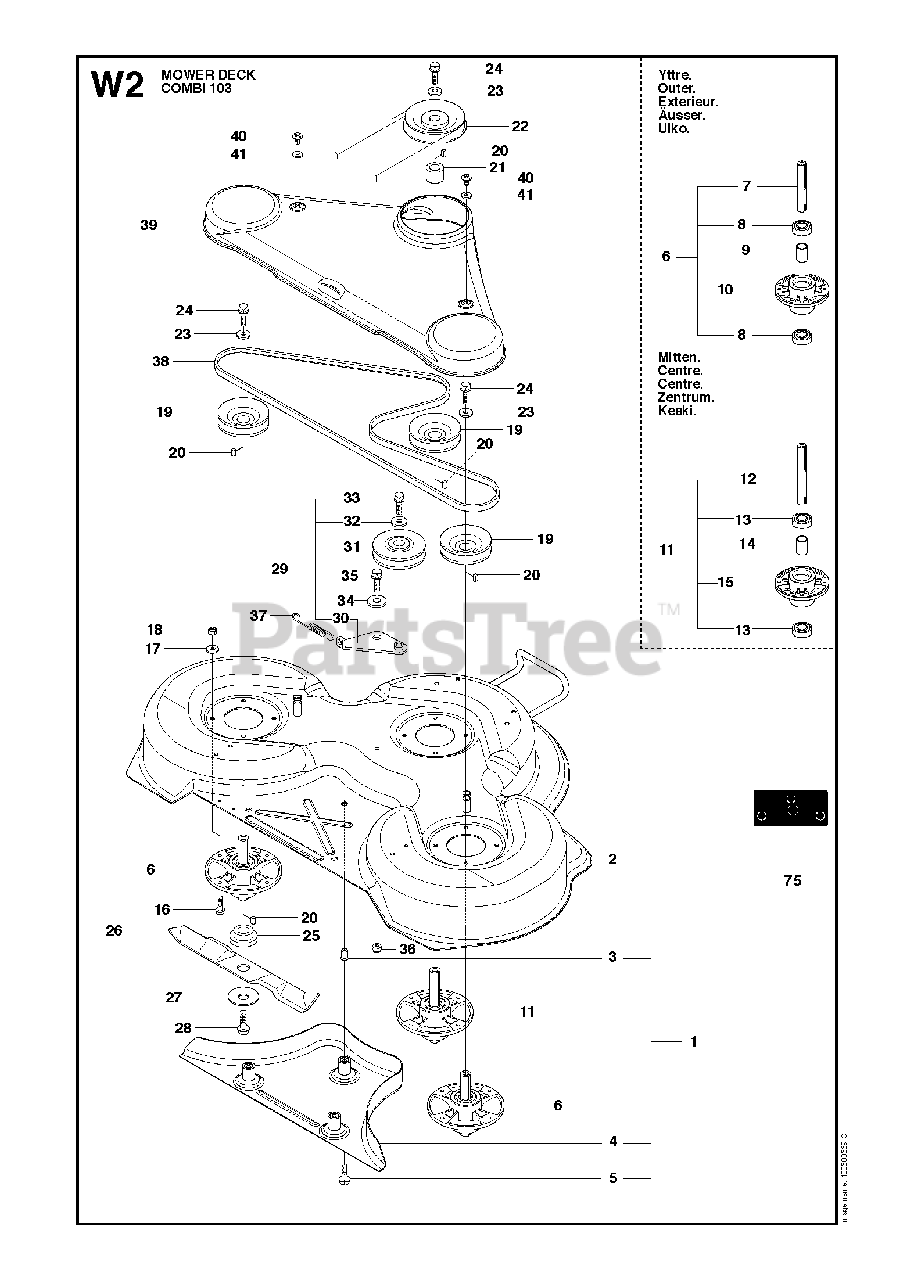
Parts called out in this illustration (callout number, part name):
3	NUT
4	PLUG
5	BOLT
6	RP SPINDLE ASSY
7	SHAFT
8	BEARING
9	SPACER
10	BEARING HOUSING
11	RP SPINDLE ASSY
12	SHAFT
13	BEARING
14	SPACER
15	BEARING HOUSING
17	WASHER BRB 8.4X17
18	LOCKNUT M8
26	BLADE
29	BELT TENSIONER ASSY
30	BELT TENSIONING ARM
31	PULLEY
32	SPACER
33	BOLT
34	WASHER
36	LOCKNUT M8
38	BELT
44	LOCKNUT M8
51	LOCKNUT M8
52	PARALLEL RODY ASSY
53	ROD
54	LINK
55	NUT
56	LINK
57	NUT
58	CLUTCH ROD ASSY
59	ROD
60	LINK
61	NUT
67	LOCKNUT M8
68	DECK ROLLER, FRONT
70	RETAINING RING SGA 15
73	WASHER
74	LOCKNUT M6
